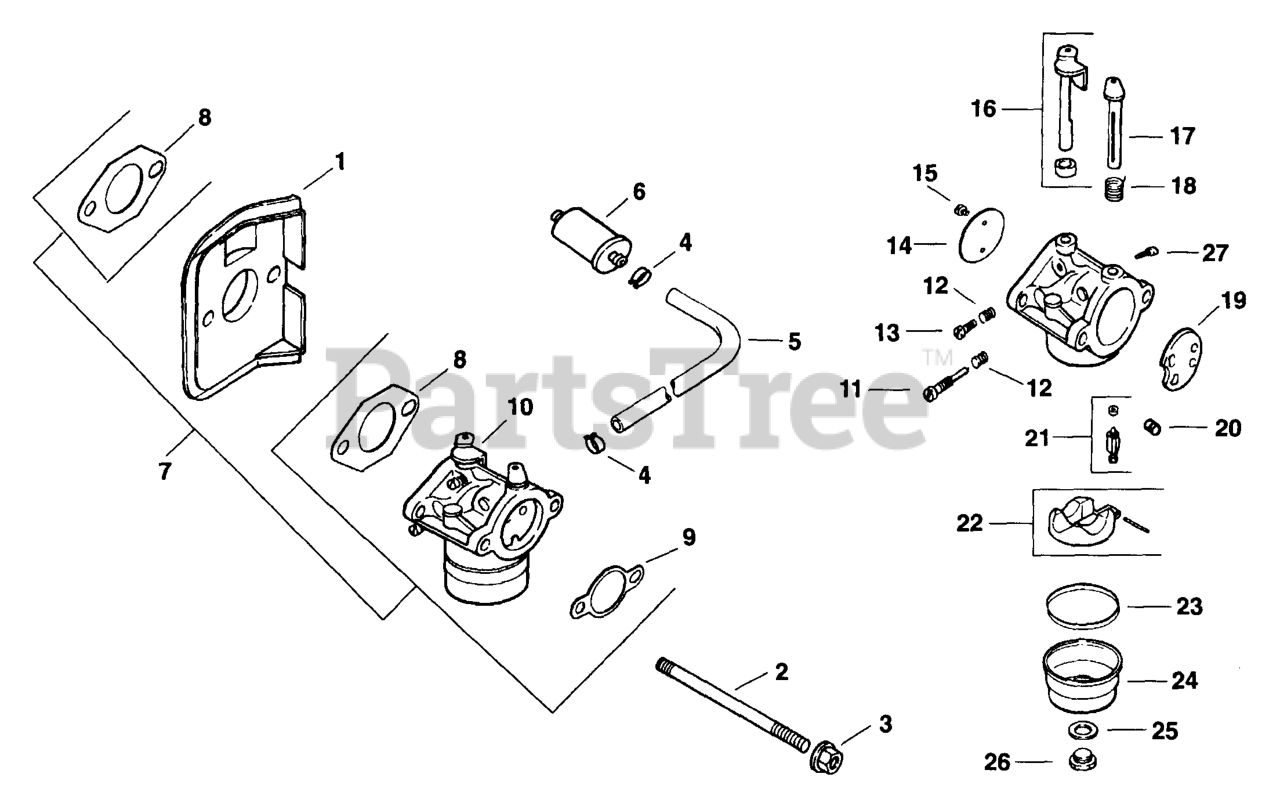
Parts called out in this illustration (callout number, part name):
1	Deflector, Heat
2	Stud, Carburetor M6x1.0x122.8
3	Nut, Hex. Flange M6x1.0
4	Clamp, Hose
6	Filter, Fuel
7	Kit, Carburetor
8	Gasket, Carburetor
9	Gasket, Air Filter
10	Carburetor Assembly
11	Needle, Idle Fuel Adjusting
12	Spring, Idle Fuel & Idle Speed Adjusting
13	Screw, Idle Speed Adjusting
14	Plate, Throttle
15	Screw, Valve
16	Shaft, Throttle W/Lever & Seal
17	Shaft, Choke
18	Spring, Choke Return
19	Plate, Choke
20	Jet, Main
21	Needle And Seat
22	Kit, Float
23	Gasket, Bowl
24	Bowl, Fuel
25	Gasket, Bowl Retainer Screw
26	Screw, Bowl Retainer
